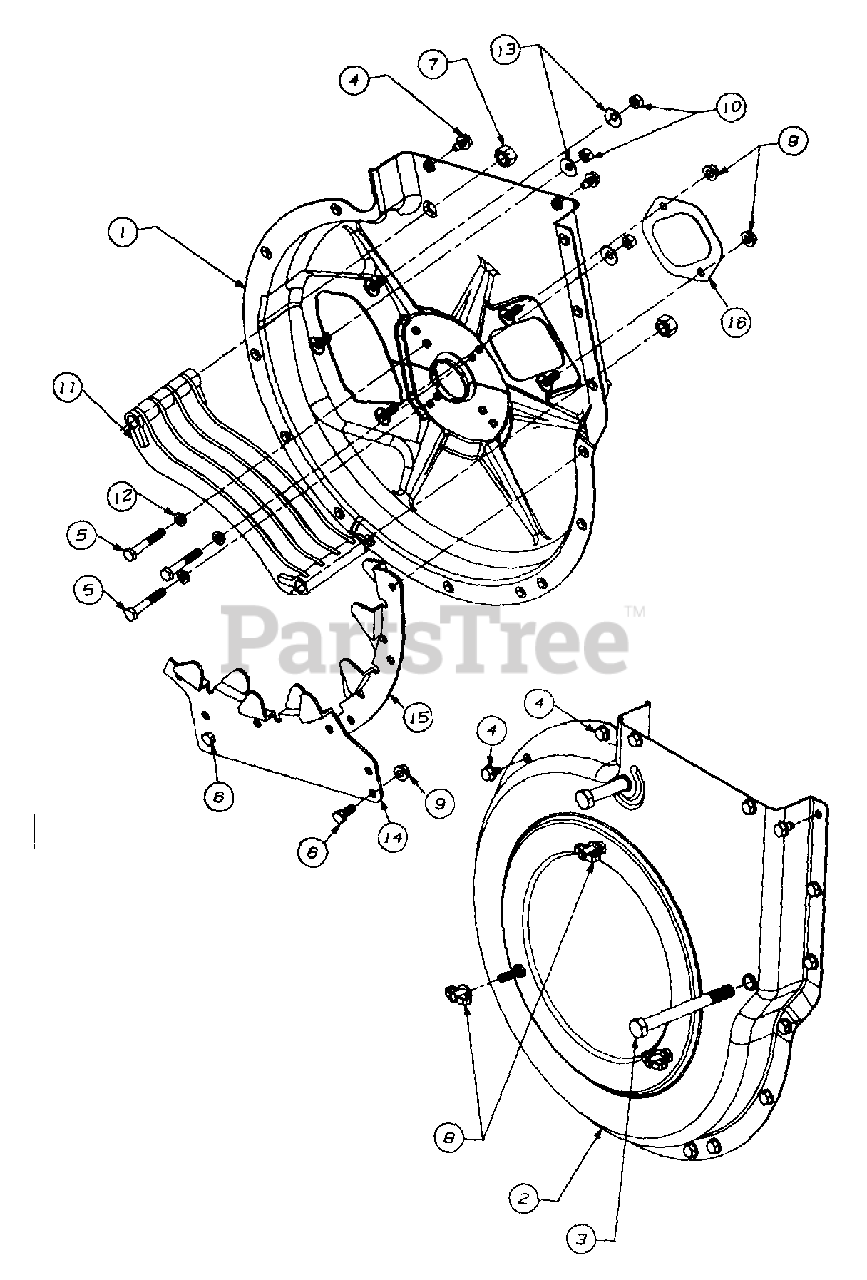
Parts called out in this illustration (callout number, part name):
3	SCREW-HEX
4	SCREW-HEX SELF TAP
5	SCREW-HEX
6	SCREW-HEX
7	NUT-HEX LOCK
9	NUT-HEX LOCK
10	NUT-HEX (OR 5)
12	WASHER-LOCK
13	WASHER-BELL
